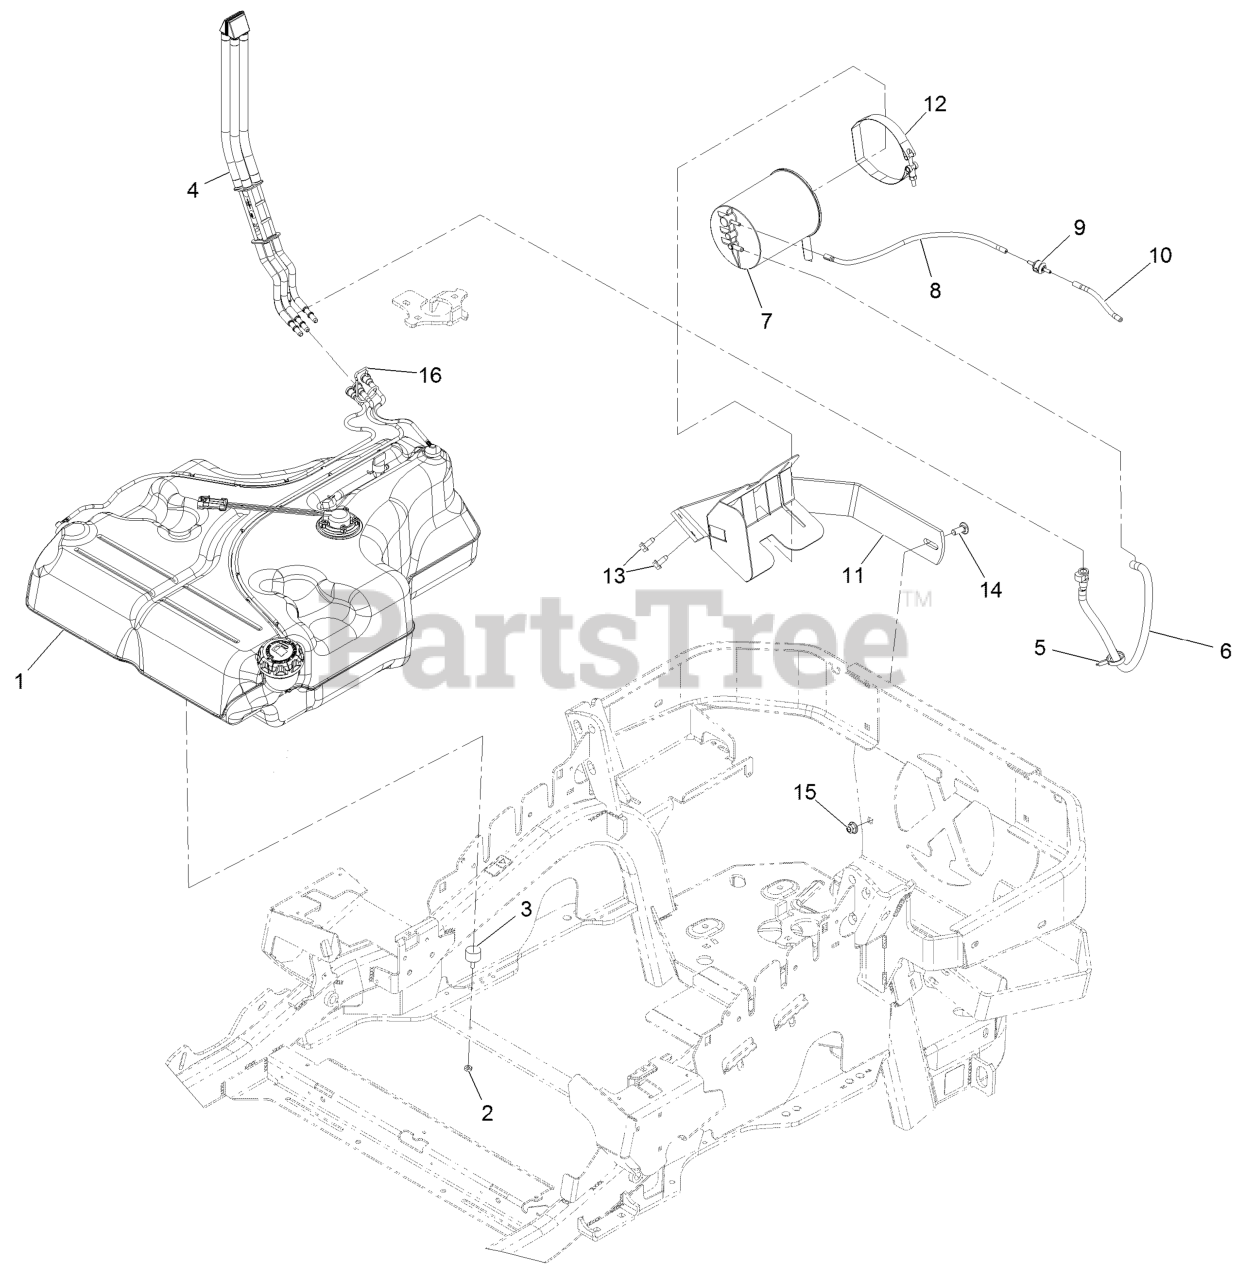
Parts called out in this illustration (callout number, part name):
2	NUT-JAM
4	FUEL MANIFOLD VENT ASM
5	CLAMP-HOSE
6	VENT HOSE ASM
7	CANISTER-CARBON, 1200CC
8	HOSE-VENT, FORMED
10	HOSE-VENT, FORMED
11	MOUNT-CANISTER
12	CLAMP, T-BOLT
13	Screw-HWH 5/16-18 X 3/4 Tf
14	SCREW-CARR
15	NUT-HF, NI
16	RETAINER-LINE, VAPOR
